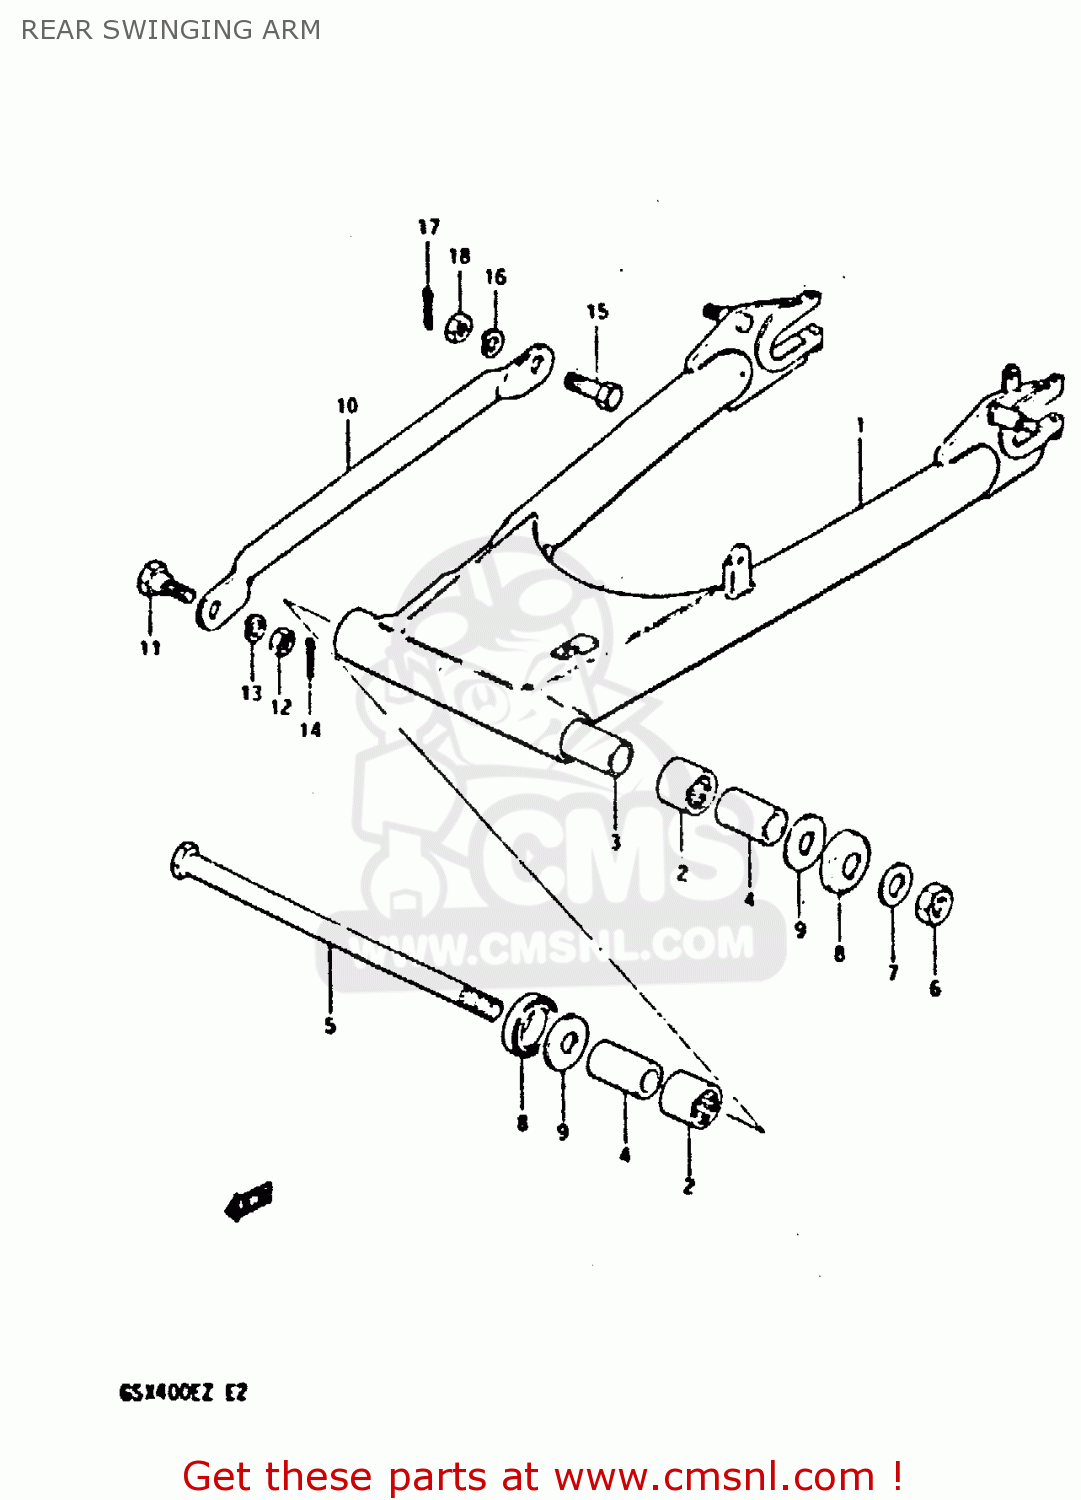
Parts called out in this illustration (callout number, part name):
1	SWING ARM ASSEMBLY,REAR
2	BEARING(22X29X30)
3	SPACER,SWINGINGARM CTR
4	SPACER,RR SWGARM PIVOT
5	SHAFT,REAR SWING ARM
6	NUT 14MM
7	WASHER
8	CVR,RR SWGARM DUST SEAL(OD:40)
9	WASHER(14.2X34X1)
10	TORQUE LINK,REAR
11	BOLT(10X24.5)
12	NUT
13	LOCK WASHER
14	PIN 20X20
15	BOLT(10X31)
16	LOCK WASHER
17	PIN 20X20
18	NUT
